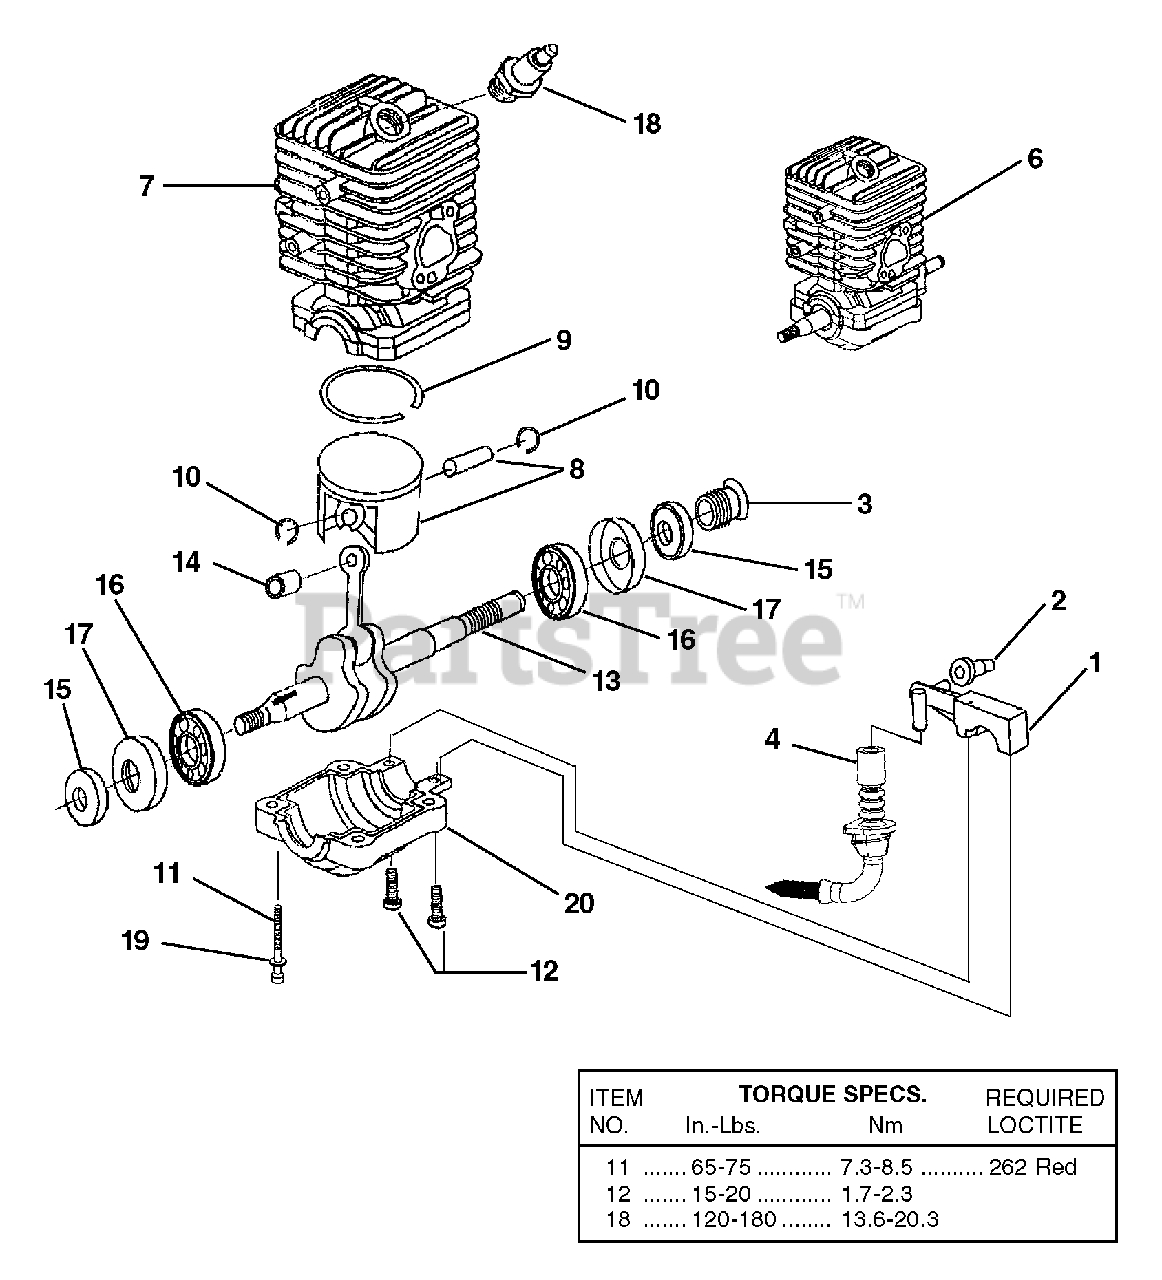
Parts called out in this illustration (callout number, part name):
1	Oil Pump Kit
2	Grommet, Oil Oultlet
3	Left Hand Worm
4	Oil Intake Tube w/filter
6	Short Block, Complete (33cc)
7	Cylinder Kit (33cc)
8	Piston & Pin
9	Piston Ring
10	Ring, Retaining
11	Screw, Cap-Socket HD.(10-24 x 2")
12	Screw, Pan HD. (8-32 x 5/8")
13	Cranshaft & Rod Assembly
14	Bearing, Needle
15	Shaft Seal
16	Bearing & Rubber Case
17	Rubber Case
18	Spark Plug
19	Washer
20	Lower Crankcase
